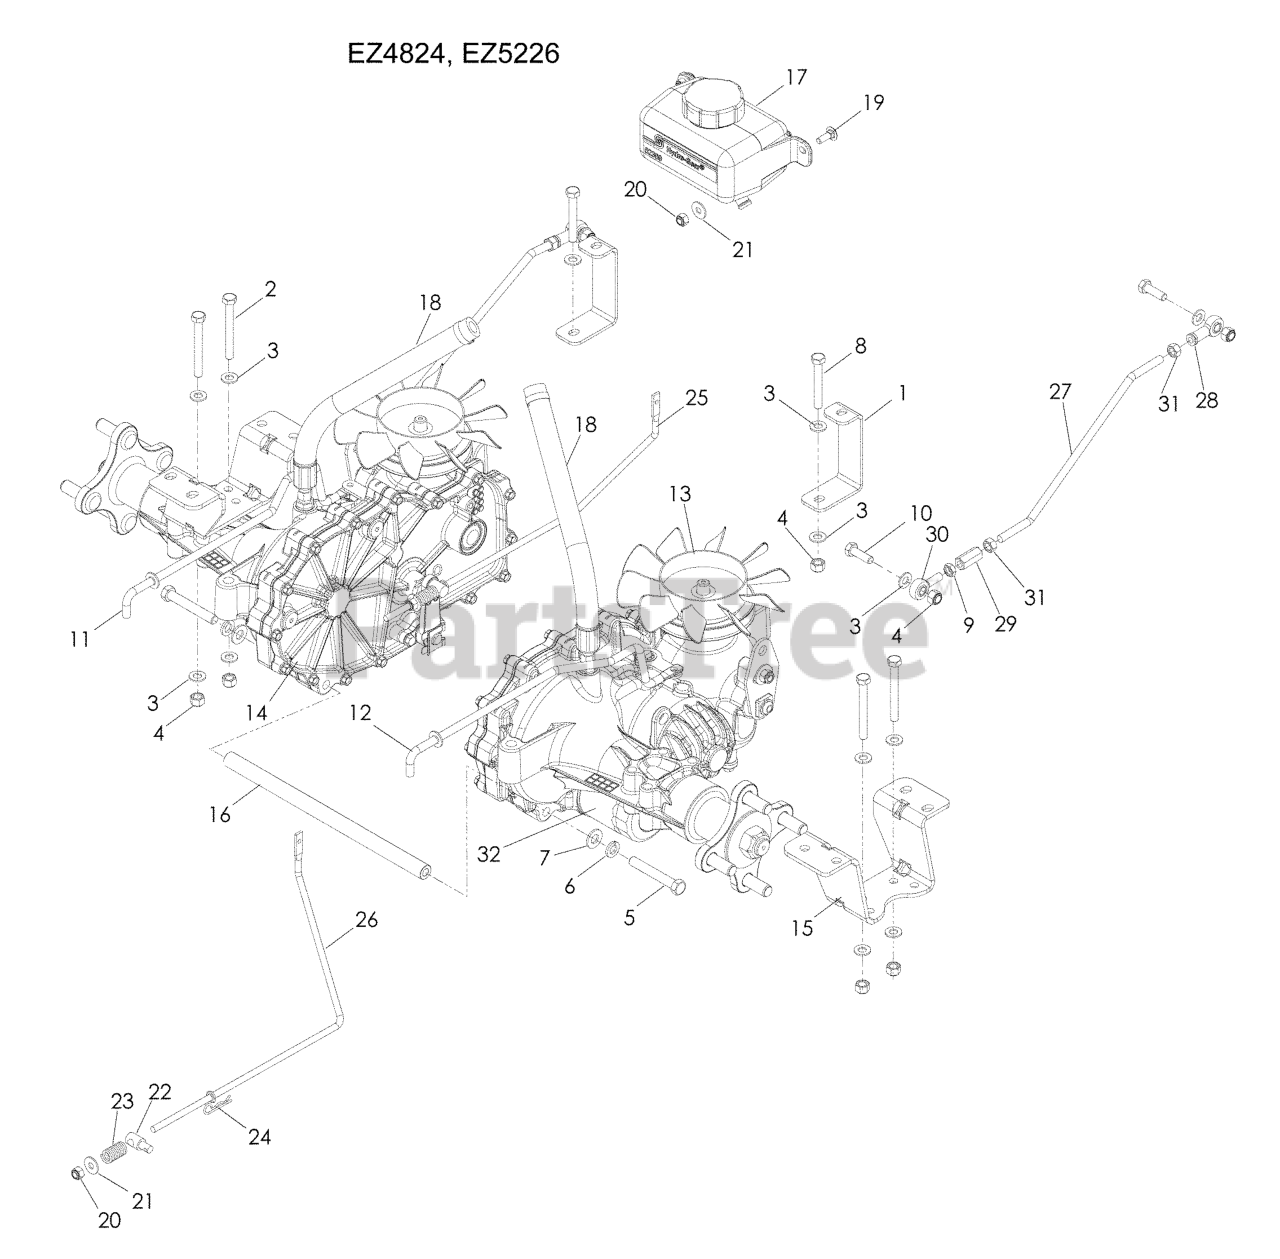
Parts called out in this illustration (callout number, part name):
1	SUPPORT.FRONT.TRANS.BLACK.
2	HCS 5/16C X 2-3/4
3	FLAT WASHER 5/16 SAE
4	NUT 5/16 NYLOC
5	HCS 3/8C X 2 1/2
6	SLW 3/8 STD
7	WASHER 3/8 SAE FLAT
9	NUT 5/16F LEFTHAND
10	HCS 5/16C X 1
11	ROD, BYPASS, RT
12	ROD, BYPASS, LT
13	HG_TRANS, ZT-2800 RT
14	HG_TRANS, ZT-2800 LEFT
15	EZT MOUNT, REAR, BLACK
16	SPACER TUBE, EZT, 11.08
17	HG_EXPANSION TANK W/CAP 71354
19	RHSNB 1/4C X 3/4
20	NUT.1/4-20.HEX.NYLOC.ZD
21	WASHER 1/4 FLAT
22	BRAKE SWIVEL
24	HAIRPIN #2
25	ROD EZT BRAKE LT
26	ROD EZT BRAKE RT
27	ROD, MOTION CONTROL
28	RH ROD END
29	ROD END COUPLER
30	RP.ROD.END.LH
32	HG_FILTER, ZT4800 52114
